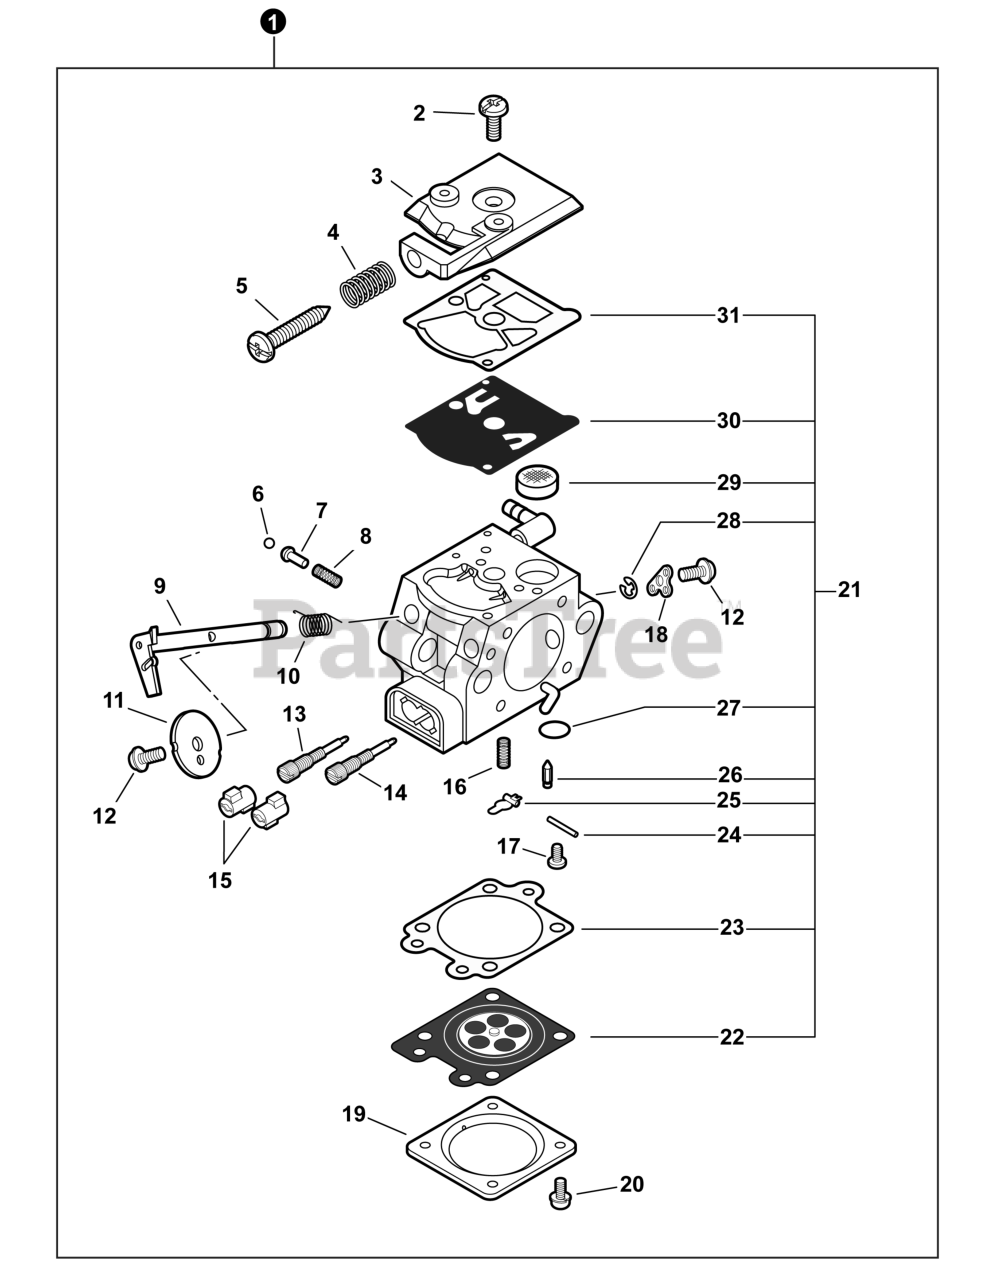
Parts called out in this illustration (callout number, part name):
1	CARBURETOR - WT-402B
3	COVER, FUEL PUMP
4	SPRING, IDLE ADJUST
5	SCREW, IDLE ADJUST
7	PISTON ASSY
8	SPRING, START VALVE
9	SHAFT, THROTTLE
10	SPRING, THROTTLE
11	VALVE, THROTTLE
13	NEEDLE, MIXTURE
14	NEEDLE, HIGH SPEED
15	CAP, LIMITER
16	SPRING, METERING LEVER
17	SCREW, METERING LEVER PIN
18	LEVER, THROTTLE
19	COVER, METERING DIAPHRAGM
21	REPAIR KIT
22	DIAPHRAGM, METERING
23	GASKET, METERING DIAPHRAGM
24	PIN, METERING LEVER
25	LEVER, METERING
26	VALVE, INLET NEEDLE
27	PLUG, WELCH
28	E-RING
29	SCREEN, FUEL INLET
30	DIAPHRAGM, PUMP
31	GASKET, FUEL PUMP
